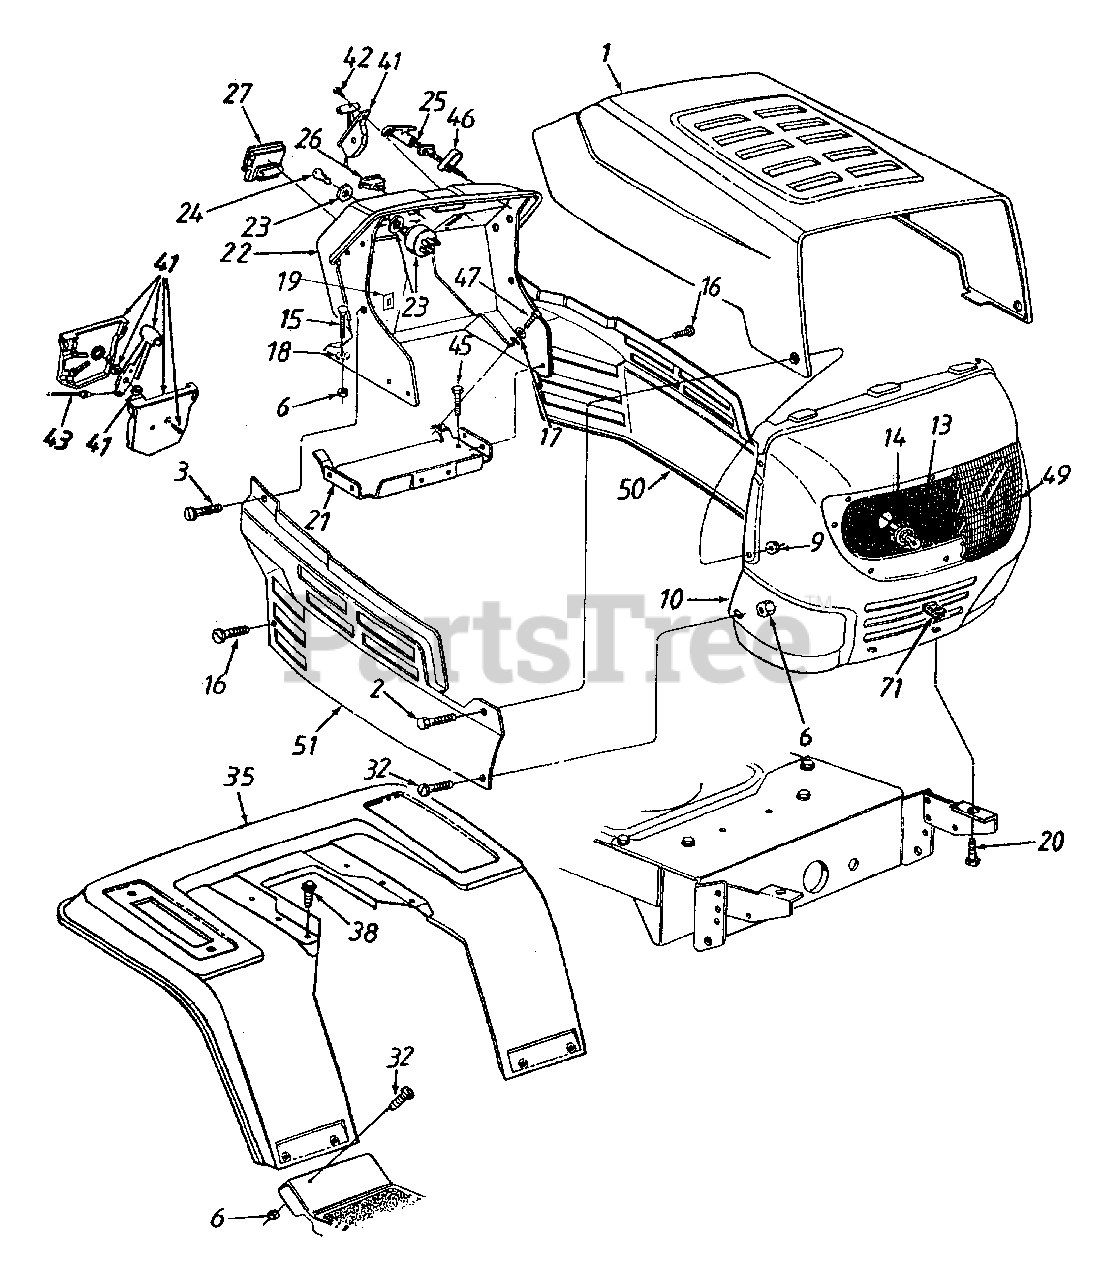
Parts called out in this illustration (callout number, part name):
6	Hex Sems Nut 1/4-20 Thd.
9	Flange Lock Nut 1/4-20 Thd.
13	Lamp
14	Socket
15	Carriage Bolt 1/4-20 x .75" Lg.
16	Hex Wash. Hd. TT-Tap Scr.1/4-20 x .5"
17	Flat Washer .281" I.D. x .73" O.D.
18	Bolt Retainer 1/4" I.D.
19	Speed Nut 1/4-20 Thd.
20	Hex Bolt 5/16-18 x .1" Lg.
23	Ignition Switch
24	Ignition Key
25	Choke Control 23" Lg.
26	Light Switch
27	Ammeter
32	Pan Hd. Scr. 1/4-20 x .75" Lg.
41	Throttle Box Assembly
42	Truss Mach. AB-Tap Scr. #10 x .5" Lg.
43	Throttle Control Wire 18.5" Lg.
45	Hex Wash. Hd. B-Tap Scr. 5/16-18 x .5"
46	Choke Retainer
47	Hex TT-Tap Scr. 1 /4-20 x .75" Lg.
49	Lens
